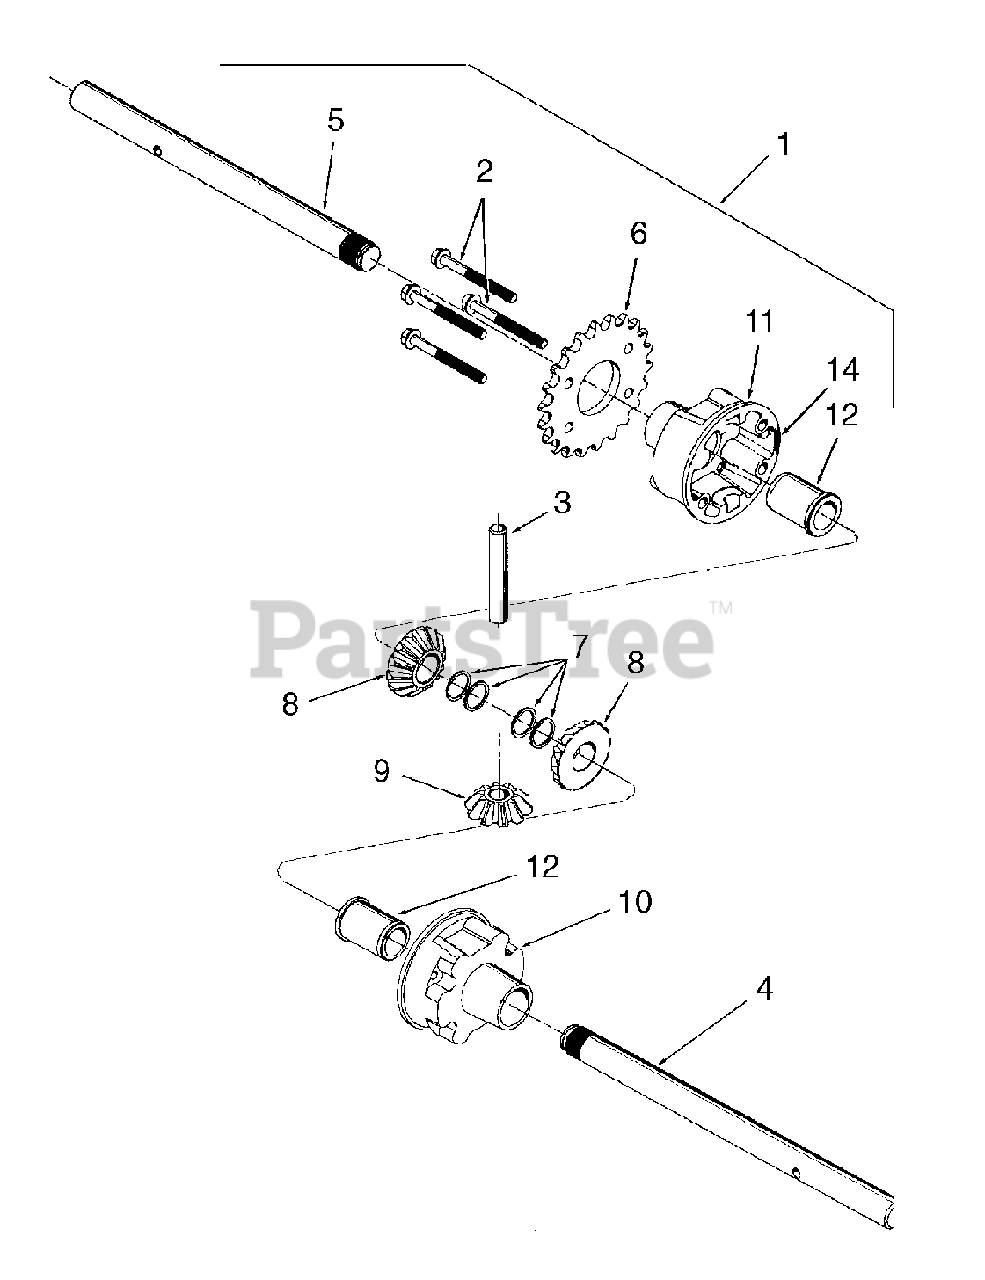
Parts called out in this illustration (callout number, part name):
1	Differential Ass'y Complete
2	Screw, Hex Wash Hd Tapp 1/4-20 x 2-5/16
3	Cross Shaft
4	Axle Shaft, .75 x 10.95
5	Axle Shaft, .75 x 9.82
6	Spocket, 22T
7	Ring, Retaining
8	Gear, Differential, 14T
9	Gear, Differential, 10T
10	Housing, Differential RH
11	Housing, Differential LH
12	Bearing, Flange, .75 ID x 1.0 OD
14	Sealant, Ultra Grey Loctite 5699
